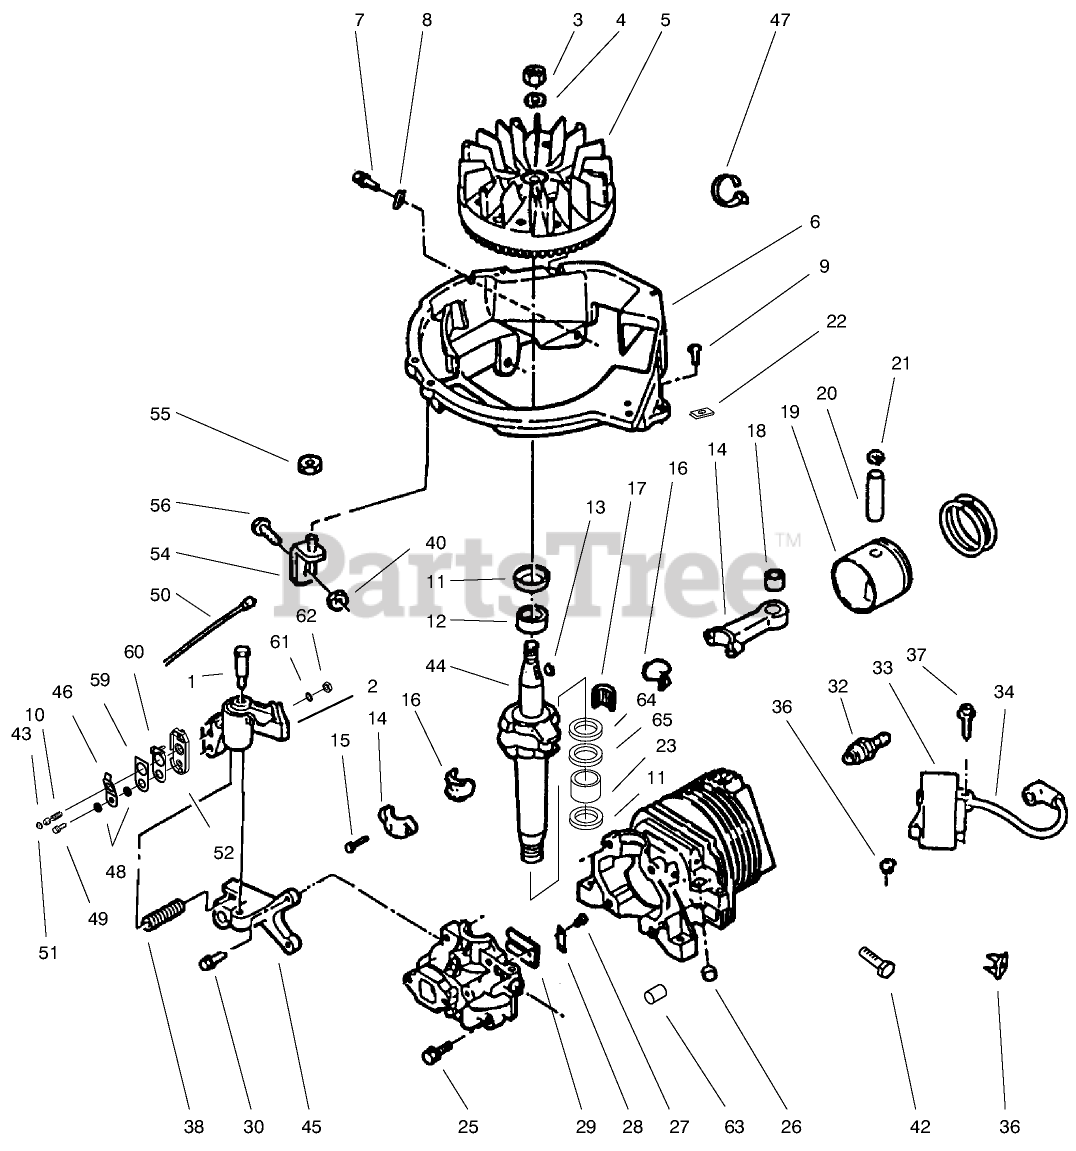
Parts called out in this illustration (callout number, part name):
1	SCREW-SHOULDER
2	BRAKE AY FE
4	WASHER-LOCK
5	FLYWHEEL ASSY F
6	BASE SHROUD F
7	SCREW F
8	"J" CLIP F
9	SCREW F
10	SPRING
11	SEAL-OIL
12	BEARING V
14	Connecting Rod Assy. (Inc 15-18)
15	SCREW-HSH
16	LINER ASM
17	Roller Strip
18	BEARING XEV
19	Piston & Ring Set (Inc 20-22)
20	PIN-WRIST VF
21	RING-RETAINING
22	NUT-SPEED
23	BEARING V
25	SCREW-H.W.HD. F
26	PLUG-CORE VF
27	SCREW-HH
28	PLATE-BACKUP, REED
29	REED-CARBURETOR
30	SCREW
32	SPARK PLUG
33	C. D. Ignition Module & Lead Assy (Incl. Ref. #34)
34	HT LEAD&COVER XEV
36	NUT-CLIP
37	SCREW F
38	SPRING-BRAKE
40	NUT-LOCK F
42	SCREW F
43	ACTUATOR-LEVER, BRAKE
44	CRANKSHAFT V
45	BRACKET-BRAKE F
46	SPRING-CONTACT
47	STRAP-TIE
48	WASHER
49	SCREW-HH
50	WIRE LEAD AY F
51	RETAINER S
52	CASE - SWITCH EF
54	BRACE AY F
55	LOCKNUT E
56	BOLT F
59	SHIELD
60	PLATE-CONTACT
61	WASHER-LOCK/EXT
63	DOWEL XEV
64	BEARING-THRUST
65	WASHER-THRUST
